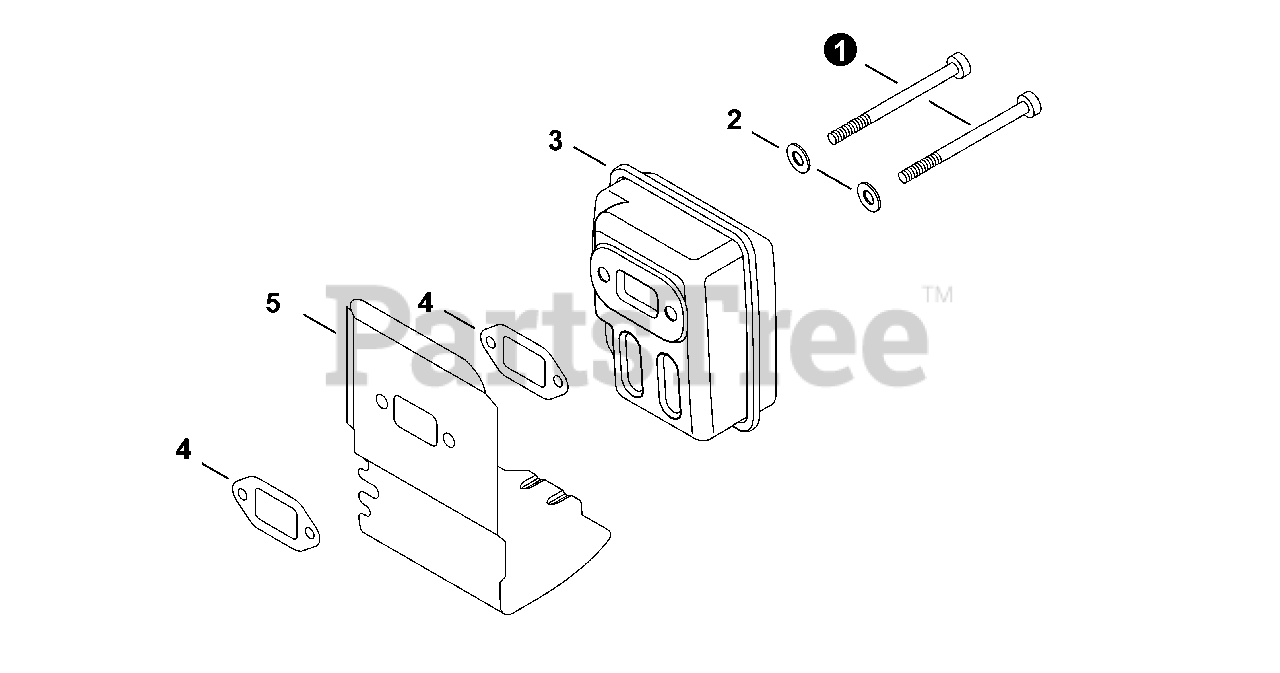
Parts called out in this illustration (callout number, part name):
1	BOLT 5x55
2	WASHER, FLAT 5.5x10x0.8
3	MUFFLER
4	GASKET, EXHAUST
5	COVER, MUFFLER
